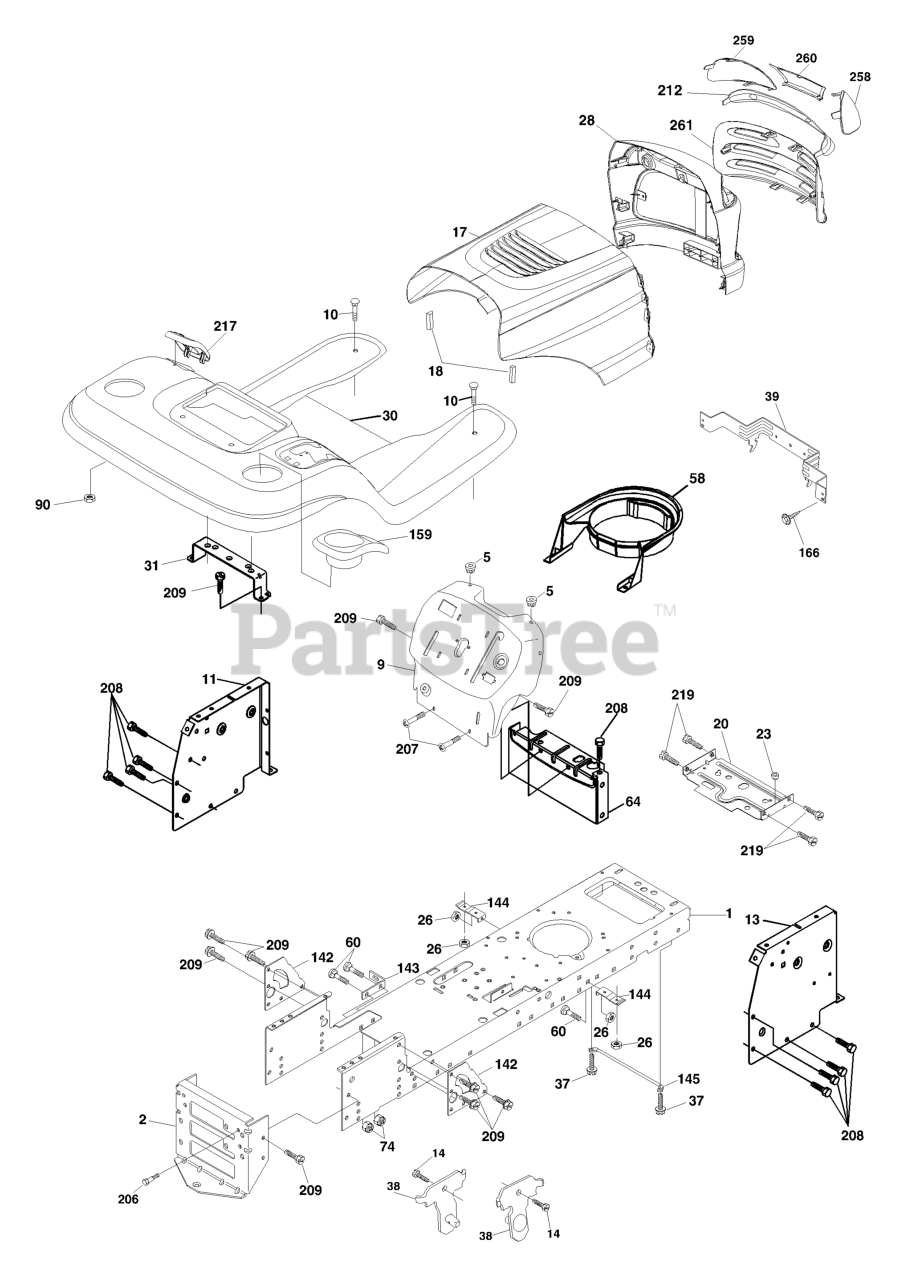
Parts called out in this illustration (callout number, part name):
1	CHASSIS STAMPING
2	DRAWBAR, 12GA
5	BUMPER.RUBBER.HOOD
9	DASH SILKSCR.
10	BOLT D
11	PANEL.DASH.LH.LTX
13	PANEL DASH RH
14	SCREW LT
17	HOOD
18	BUMPER.HOOD.LARGE.1.75"
20	PLATE MTG.BATTERY/FUEL TANK
23	BUSHING.SNAP.NYL.BLK.
26	NUT
28	GRILL/LEN.ASM.DL.HUSQ
30	FENDER
31	BRACKET.SUPPORT.FENDER
37	Screw Thdrol 5/16-18 x 1/2
38	BRACKET.ASM.PIVOT.MOWER.REAR
39	BRACKET PIVOT LASER
60	Bolt RDHD SQNK 3/8-16 x 3/4
64	DASH LOWER
90	NUT.PUSH.3/16
142	PLATE REINFORCEMENT
143	BRACKET, SWAYBAR CHASSIS
144	BRKT, FOOT REST
145	ROD PIVOT CHASSIS/HOOD
159	GREY CUP HOLDER
166	SCREW
206	SHOULDER BOLT 5/16-18TT
207	SCREW, 5/16-18 X 1/2
208	SCREW 3/8-16X1/2
209	SCREW, 3/8-16X3/4
212	INSERT.LENS.REFLECTIVE
217	CONSOLE FUEL WINDOW
219	SCREW
258	LENS LH
259	LENS LH
260	COVER.LENS.HUSQ.( HAVE GRAY)
261	INSERT GRILLE
